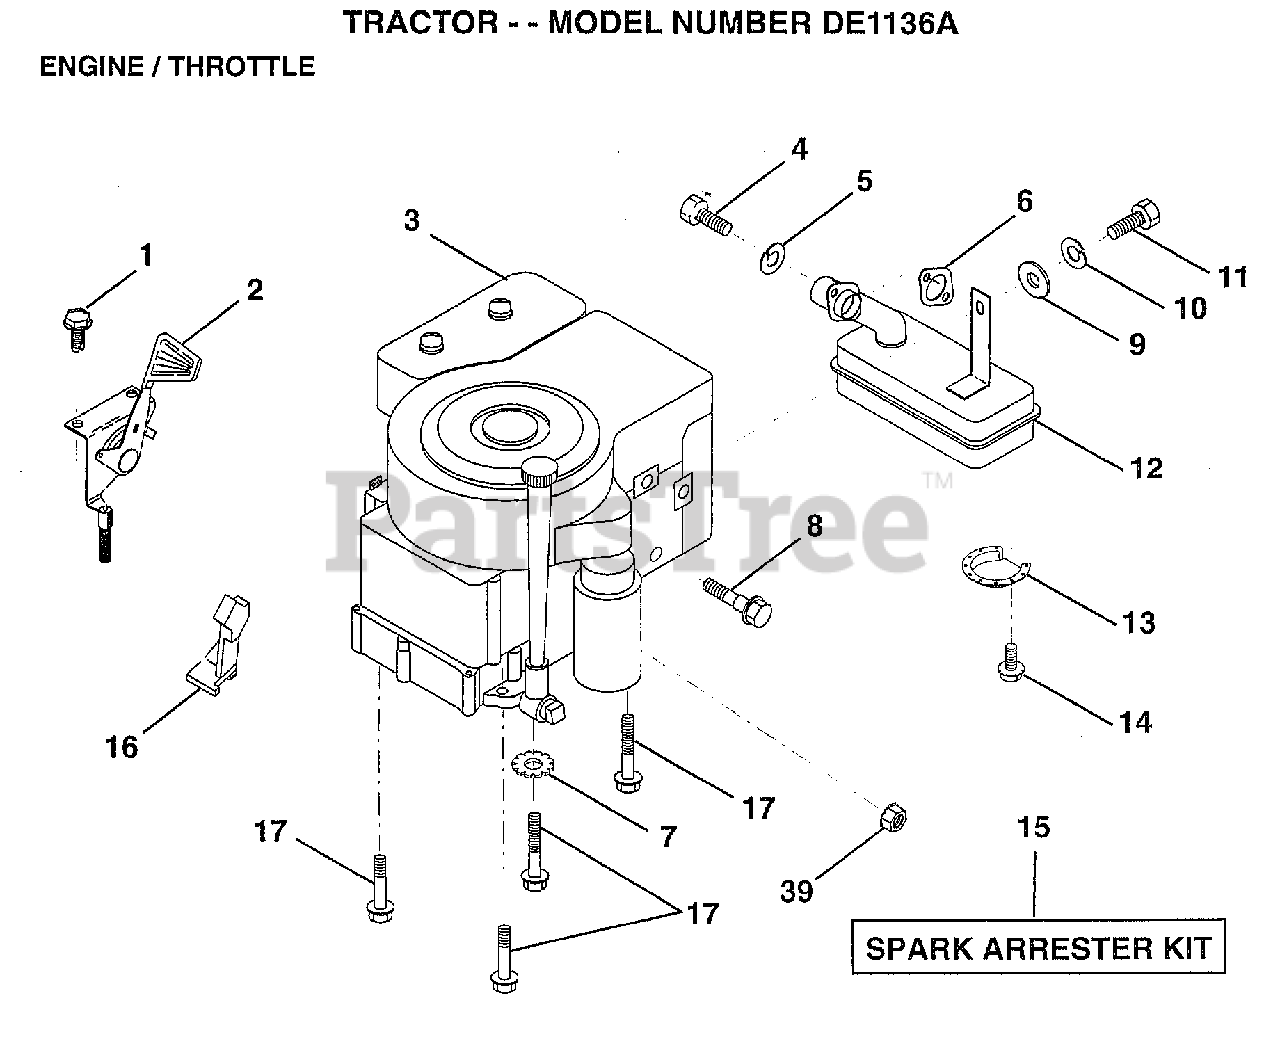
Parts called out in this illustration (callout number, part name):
1	SCREW.1/4-20X1/2
4	SCREW
5	LOCKWASHER
7	LOCKWASHER
8	BOLT T
10	LOCKWASHER
12	MUFFLER
13	DEFLECTOR.222573
16	"STOP,DASH THROTT"
17	SCREW LT
39	NUT
